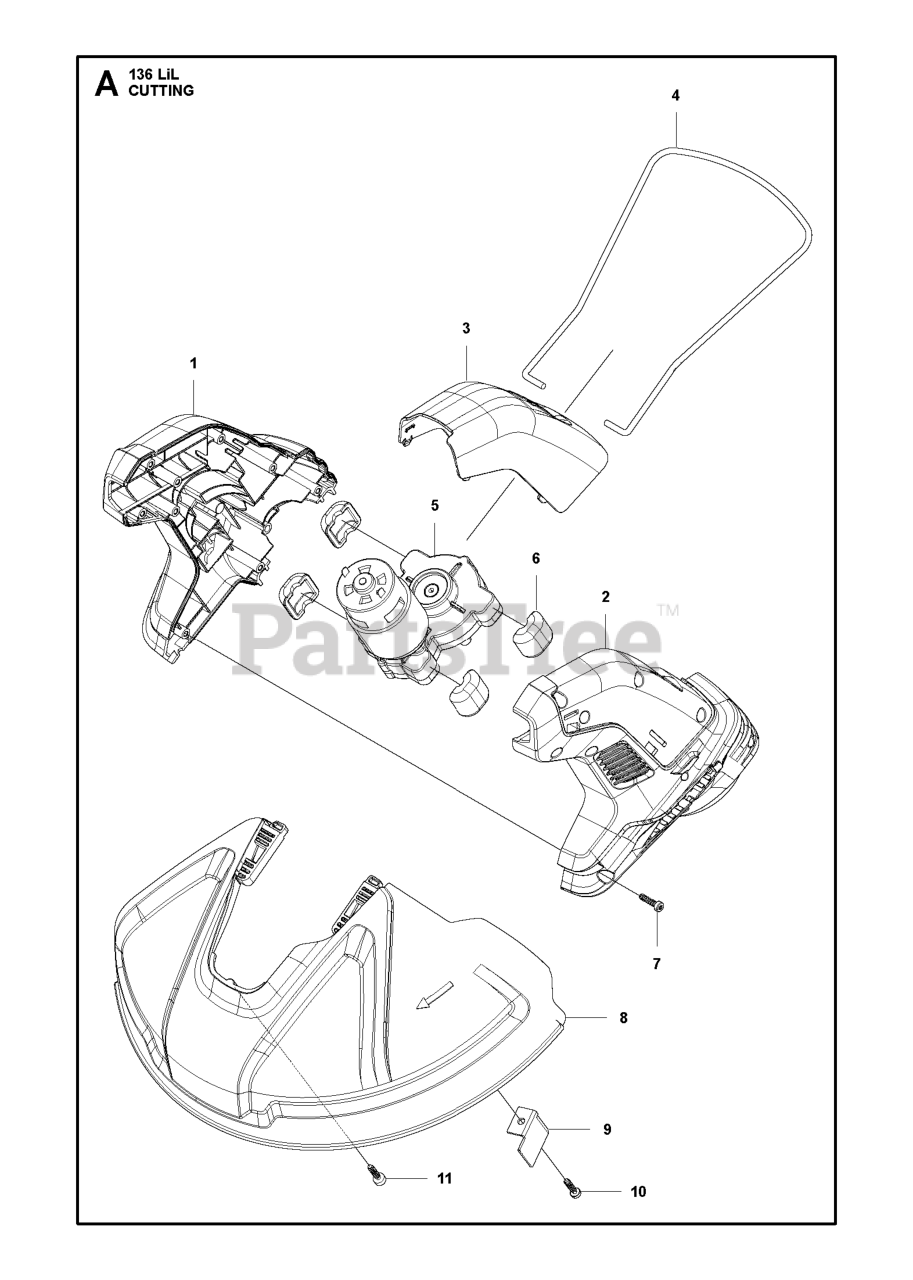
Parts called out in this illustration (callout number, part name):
1	HOUSING MOTOR HOUSING L
2	HOUSING MOTOR HOUSING R
3	COVER MOTOR HOUSING
4	RING PLANT GUARD
5	GEAR GEAR BOX ASSEMBLY
7	SCREW ST4X16
8	GUARD FOR CUTTING HEAD
9	BLADE 330MM
10	SCREW ST4X16
11	SCREW ST4*16
